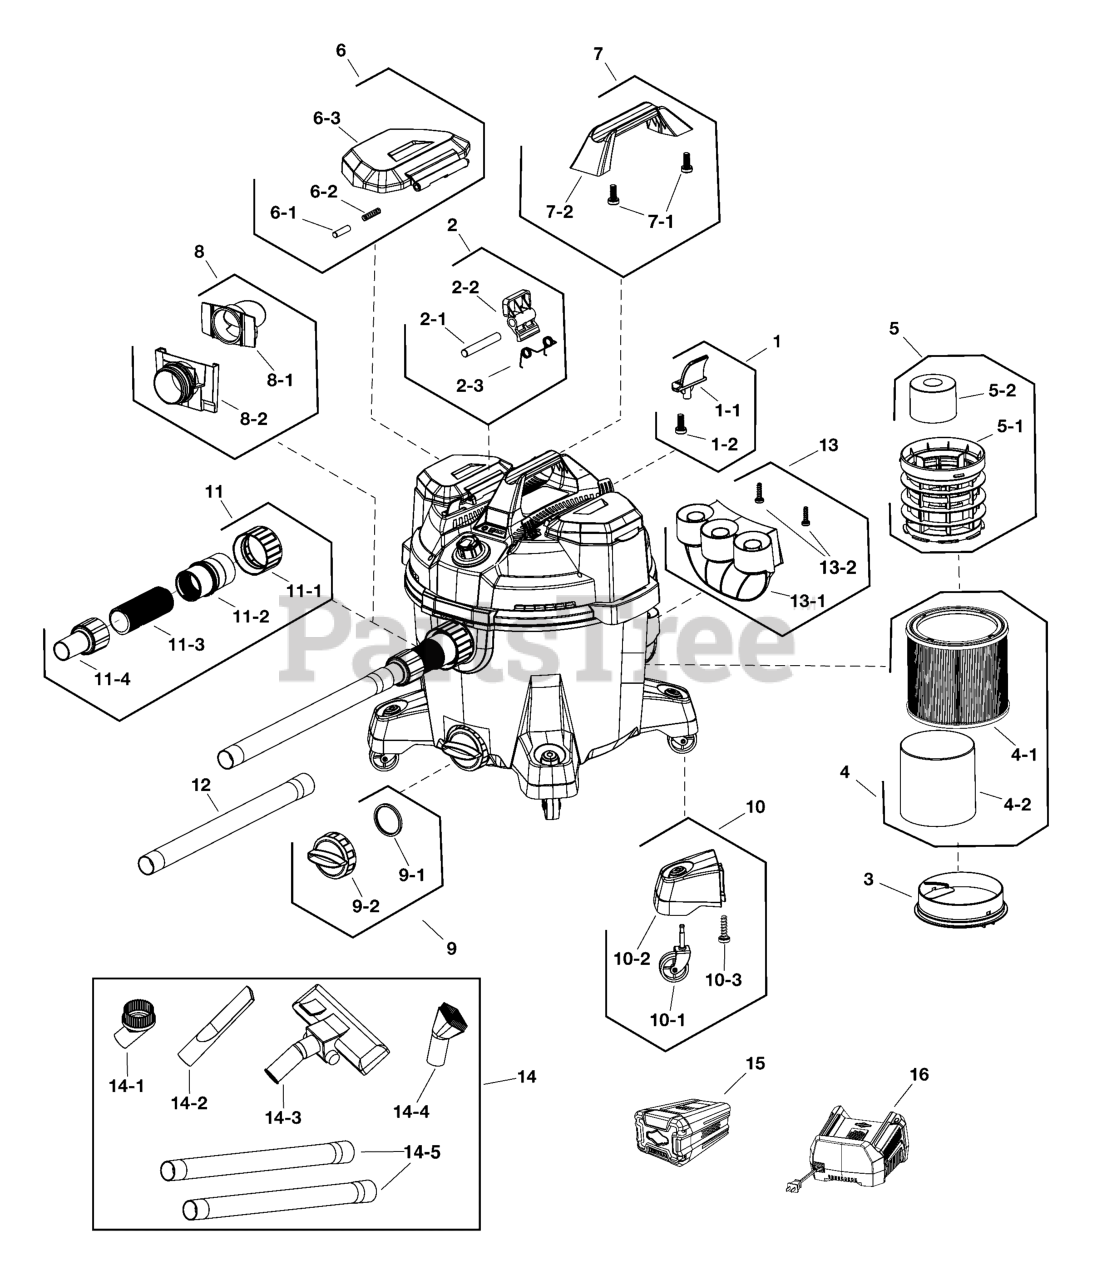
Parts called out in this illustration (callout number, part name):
1	BRACKET, Hose
1-1	BRACKET, Hose
2	KIT, Battery Release
2-1	PIN
2-2	BUTTON, Battery Releasee
2-3	SPRING, Torsion
3	RETAINER, Filter
4	FILTER, Cartridge
4-1	FILTER, Hepa
4-2	SPONGE, Filter
5	KIT, Filter Cage
5-1	CAGE, Filter
5-2	FLOAT
6	KIT, Cover
6-1	PIN
6-2	SPRING, Compession
6-3	COVER, Battery
7	KIT, Handle
7-1	HANDLE
8	KIT, Inlet Deflector
8-1	DEFLECTOR, Bag
8-2	COVER, Dust
9	KIT, Cover, Drain
9-1	GASKET
9-2	COVER, Drain
10	KIT, Caster Wheel
10-1	WHEEL, Caster
10-2	COVER, Wheel
11	KIT, Hose
11-1	RING, Locking
11-2	Connector, Hose
11-3	Hose
11-4	Outlet, Hose
12	WAND, Extension
13	TRAY, Accessory
13-1	TRAY, Accessory
14	KIT, Cleaning
14-1	BRUSH, Upholstery, Round
14-2	Tool, Cervice
14-3	BRUSH, Floor
14-4	BRUSH, Upholstery, Square
14-5	WAND, Extension
15	* BATTERY, 2.0, 82V NA
16	* CHARGER, Battery, NA
